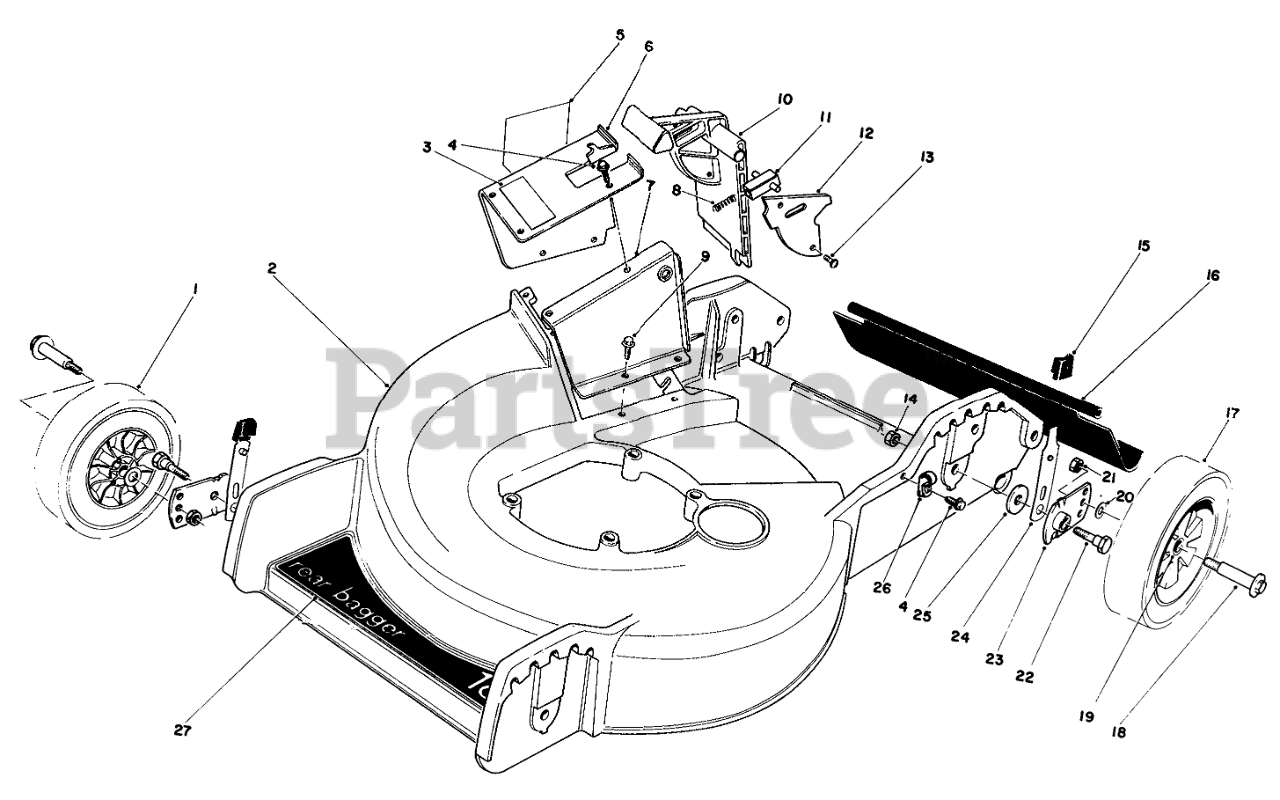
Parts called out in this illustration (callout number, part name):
1	Wheel & Tire Assembly (Incl. Ref. #18)
2	Housing
3	Decal-Door
4	SCREW
5	DECAL-DANGER
6	Tunnel-Outer (Incl. Ref. #4 & 5)
7	Tunnel-Inner
8	SPRING-COMPRESSION, LATCH
9	SCREW
10	Door Mulching
11	Door Latch
12	Cover Door
14	NUT-LOCK, NI
15	KNOB-ARM
16	SHIELD - TRAILING
17	Wheel & Tire Assembly (Incl. Ref. #18)
18	BOLT-WHEEL
19	BUSHING
20	WASHER
21	Nut
22	PIVOT SCREW
23	PIVOT ARM ASSY
24	SPRING ARM ASM
25	PIVOT WASHER
26	CLAMP-NYLON
27	DECAL-DECK
